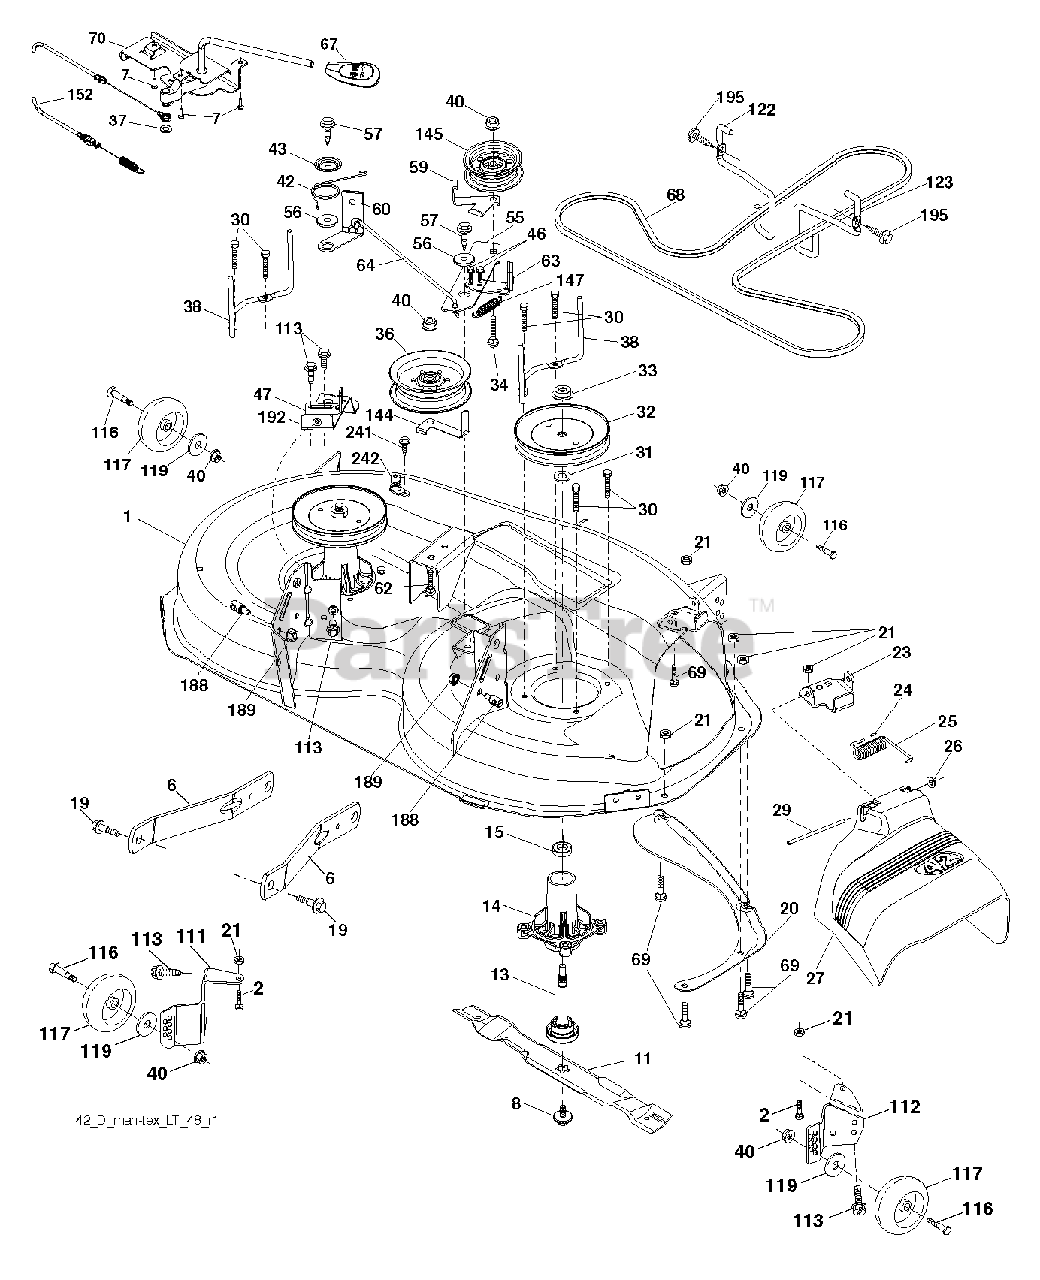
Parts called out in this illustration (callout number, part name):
6	ARM.SUSPENSION.MOWER.R
7	SCREW.#10 X 0.750.BOS THREAD
8	BOLT.WASHER.ASM.7/16-2
11	42" HI-LIFT BLADE
13	SHAFT.ASM.MDRL.N/GREASE.38
14	HOUSING MANDREL
15	BEARING
19	BOLT.SHOULDER
20	BAFFLE VORTEX
23	BRKT.DEFLECTOR.38"2005
24	CAP-SLEEVE LT
25	SPRING.TORSION.DEFLECT
26	NUT PUSH M
29	HINGE ROD
30	SCREW, WASHER HEAD
33	NUT.FLANGE.LOCK.TOP
37	WASHER
46	SCREW 1/4-20X5/8
56	SPACER.RETAINER
57	SCREW 3/8-16X1
59	GUARD
69	BOLT
116	BOLT M
117	WHEEL GAGE.HALF.SPOKED
145	PULLEY.IDLER.48"PRIMARY
188	STUD.FASTNER.W/D.ANTI-
189	NUT LOCK HEX FLANGE 5/16-18
195	SCREW, 3/8-16X3/4
242	PORT.WASHOUT
